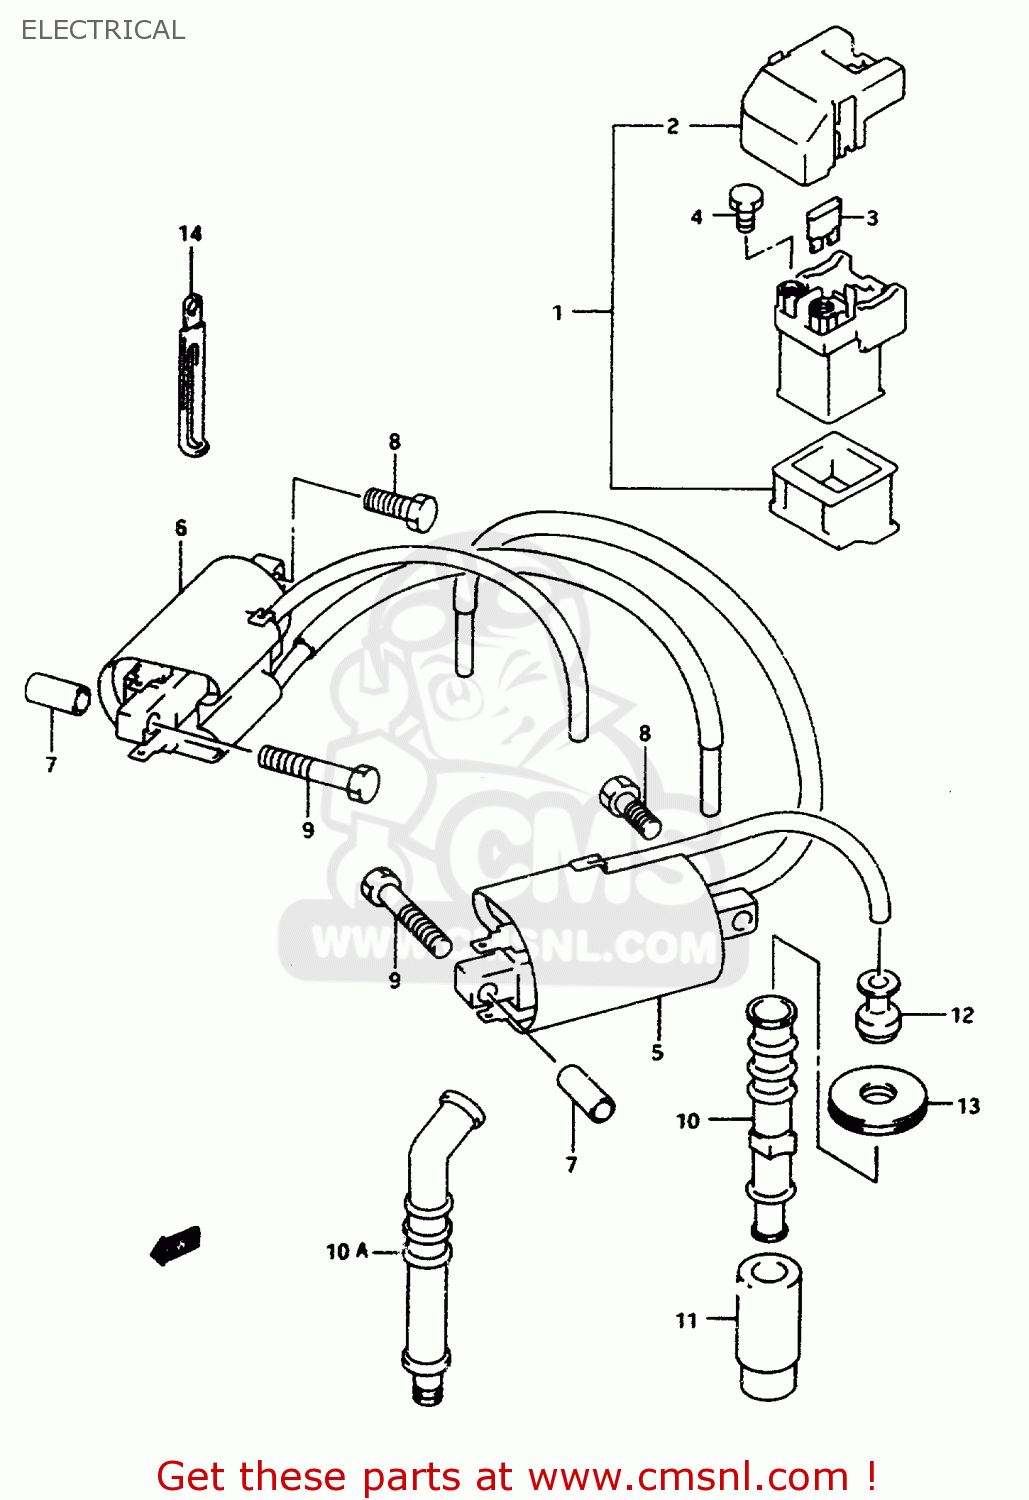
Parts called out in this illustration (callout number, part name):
1	RELAY ASSY,STARTING MOTOR
2	COVER,RELAY ASSEMBLY
3	FUSE(30A)
4	SCREW(6X8)
5	COIL ASSEMBLY,IGNITION NO
6	COIL ASSEMBLY,IGNITION NO
7	SPACER(6.2X15.5X16.5)
8	BOLT
9	BOLT
10	CAP,SPARK PLUG
10A	CAP ASSY,SPARK PLUG
11	SEAL,SPARK PLUG
12	SEAL,HIGH TENSION CORD
13	COVER,SPARK PLUG CAP
14	CLAMP
